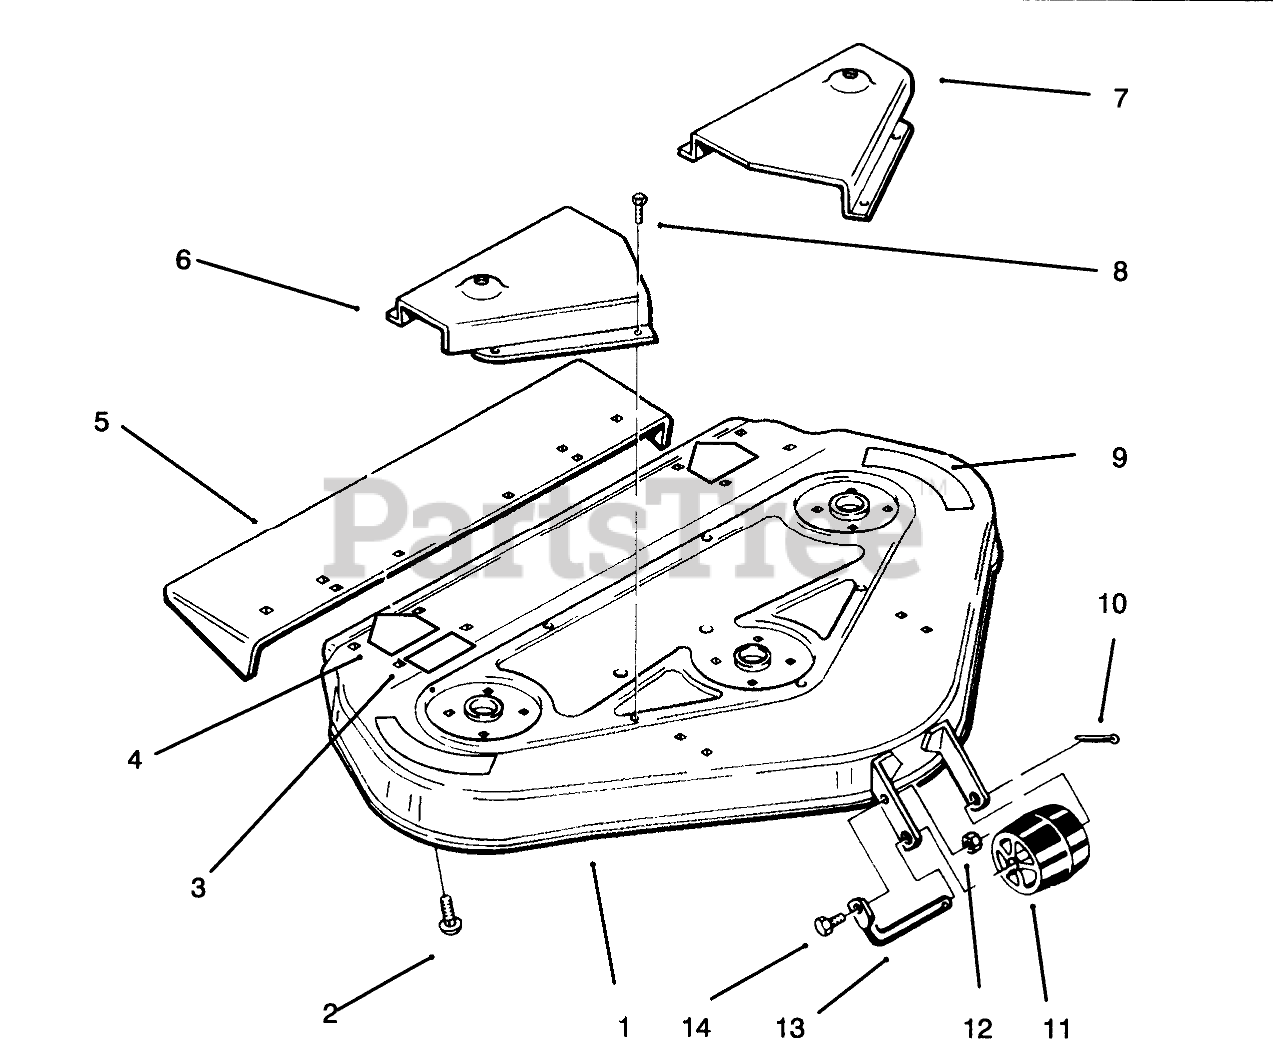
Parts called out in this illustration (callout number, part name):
1	Deck (Incl. Ref. #4 9)
2	BOLT-CARR
3	DECAL-HEIGHT & BELT
4	DECAL-DANGER
9	DECAL - DANGER
10	PIN-COTTER
12	NUT-LOCK, NI
13	ROLLER-SHAFT
14	SCREW-HH
